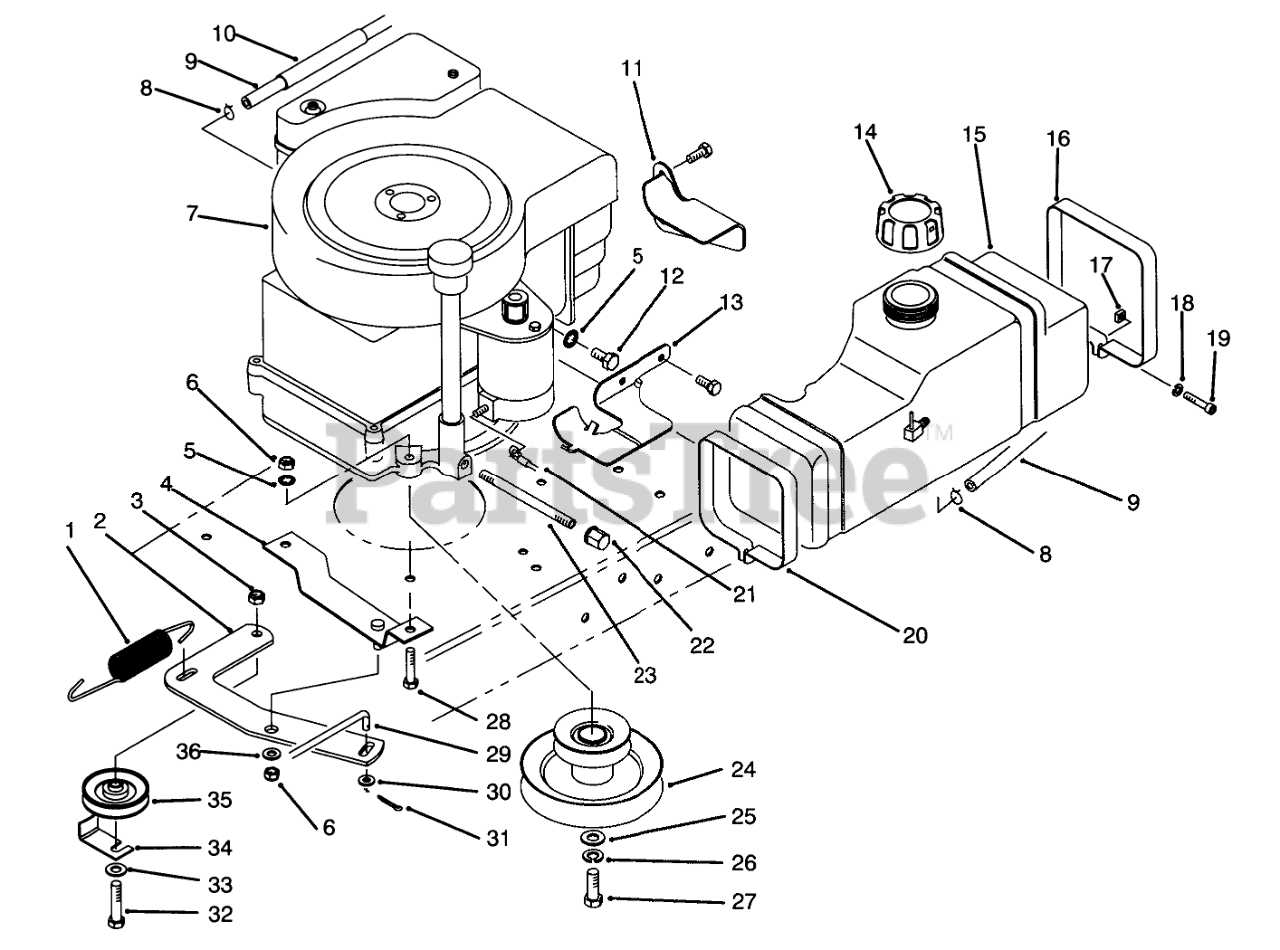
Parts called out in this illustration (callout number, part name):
1	SPRING-TRACTION
2	Plate-Mounting, Idler
3	NUT-LOCK, NI
4	Bracket W.A.-Traction
5	WASHER-LOCK, INTERNAL
6	NUT-LOCK, NI
8	CLAMP-HOSE
9	HOSE-FUEL
9	HOSE -RETURN
9	HOSE - FUEL
10	SUPPORT-FUEL LINE
11	REAR TANK MTG BRKT B
12	SCREW-HWHTF
13	FRT TANK MTG BRKT B
14	GAS CAP ASM
15	TANK-5 QT GAS
16	Retainer-Front
17	NUT-SQUARE
18	WASHER-LOCK
19	SCREW-HSH
20	Retainer-Rear
21	WIRE ASM
22	CAP-PIPE
23	NIPPLE
24	PULLEY-ENGINE
25	WASHER-FLAT
26	WASHER-LOCK
27	SCREW-HH
28	SCREW-HH
29	ROD-TRACTION
30	WASHER-FLAT
31	PIN-COTTER
32	SCREW-HH
33	WASHER-FLAT
34	RETAINER-BELT
35	PULLEY-IDLER
36	WASHER-FLAT
